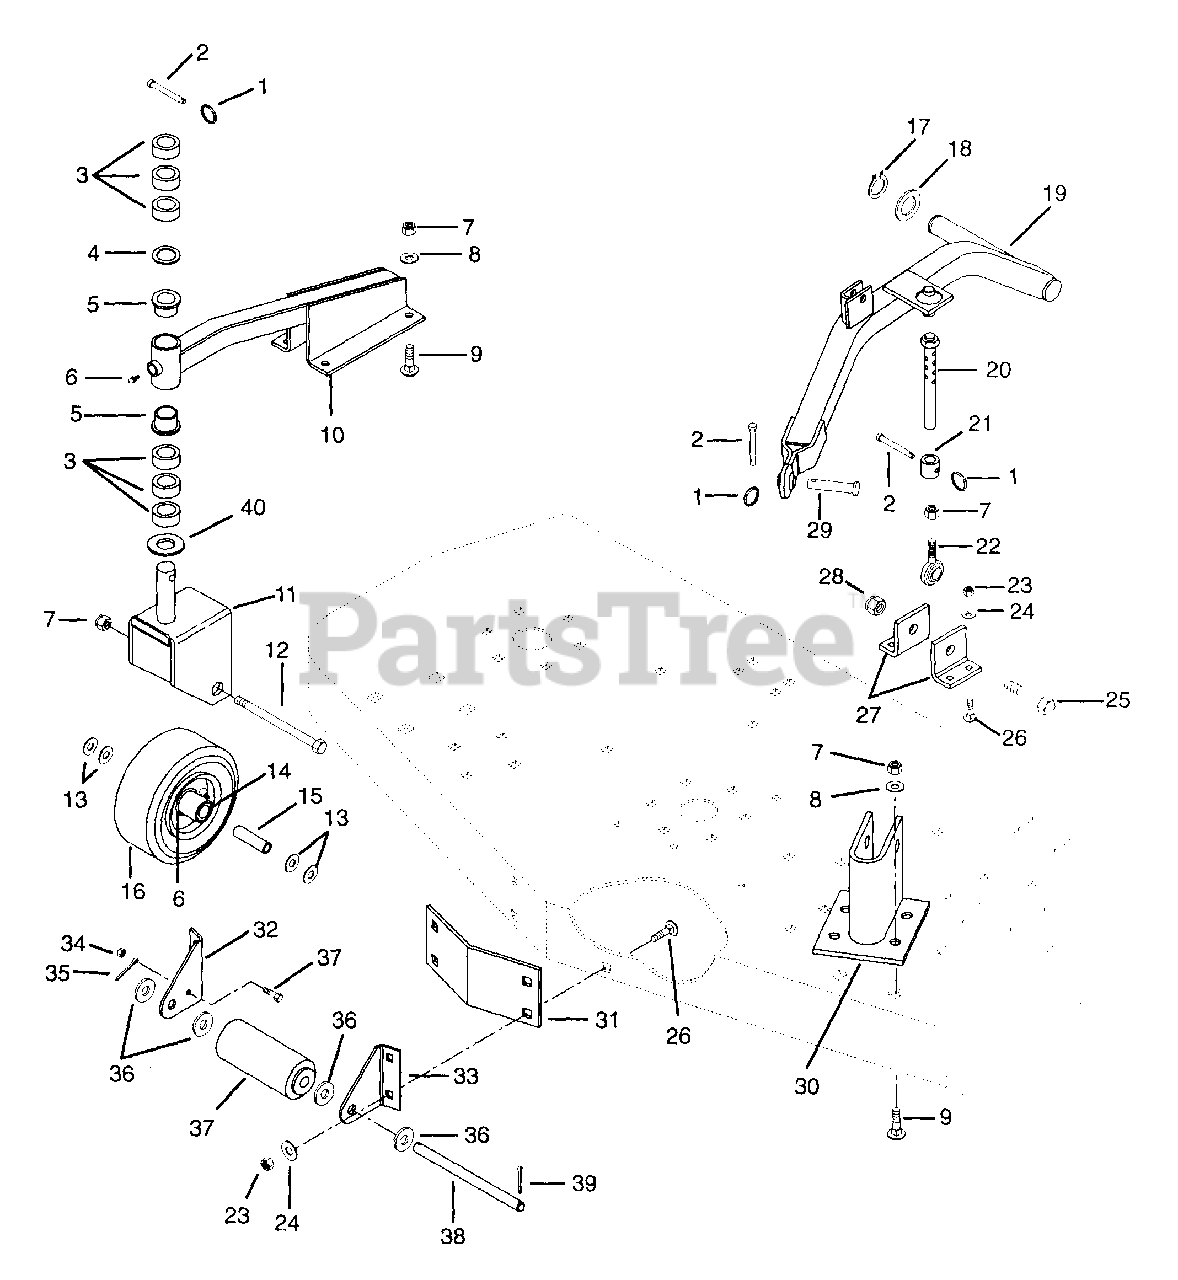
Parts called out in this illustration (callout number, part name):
1	Ring-Retaining-External 1.062 x 1.25
2	Pin-Clevis .313 x 2.62 Grade 5
3	Bushing Sleeve 1.04 x 1.75 x .500
4	Washer-Hardened Thrust 1.002 x 1.552 x .030
5	Bushing-Flange 1.02 x 1.385 x .75 x 1.75
6	Fitting-Lube .25-28 x .256
7	Nut-Lock-Nylon .50-13 Grade 5
8	Washer-Flat-Steel .531 x 1.062 x .095
9	Bolt-Round Head Square Neck .50-13 x 1.50
10	Weldment, Caster Wheel Support (005,006,301,302)
10	Weldment, Wheel Mounting Right Hand (004,300)
10	Weldment, Wheel Mounting Left Hand (004,300)
11	Weldment, Caster Fork
12	Bolt-Hex .50-13 x 5.50
13	Washer-Flat-Steel .531 x 1.250 x .100
14	Bearing, Ball .752 x 1.50 x .50
15	Spacer .532 x .748 x 3.34
16	Wheel 9 x 3.50
17	Ring-Retaining-External 1.5 x 1.38
18	Washer-Thrust 1.502 x 2.18 x .063
19	Weldment, Mower Mounting Arm Left Hand
19	Weldment, Mower Mounting Arm Right Hand
20	Weldment, Height Adjustment
21	Spacer .765 x 1.25 x .910
22	Rod, End
23	Nut-Locking-Nylon .375-16 Grade 2
24	Washer-Flat-Steel .406 x .812 x .065
25	Bolt-Hex .75-10 x 3.50
26	Bolt-Round Head Square Neck .38-16 x 1.0
27	Bracket, Deck Support Rear
28	Nut-Locking-Nylon .75-10 Grade 2
29	Pin-Clevis .875 x 3.00
30	Weldment, Mower Mounting Arm Bracket (005,006,301,302)
31	Plate, Deck Reinforcement
32	Bracket, Roller Right Hand
33	Bracket, Roller Left Hand
34	Nut-Locking-Nylon .250-20 Grade 2
35	Pin-Cotter .250 x 2.00
36	Washer-Flat-Steel .656 x 1.312 x .095
37	Roller, Gauge
38	Shaft, Center Roller
39	Pin-Cotter .25 x 1.00
40	Washer-Flat-Steel 1.007 x 1.542 x .062
